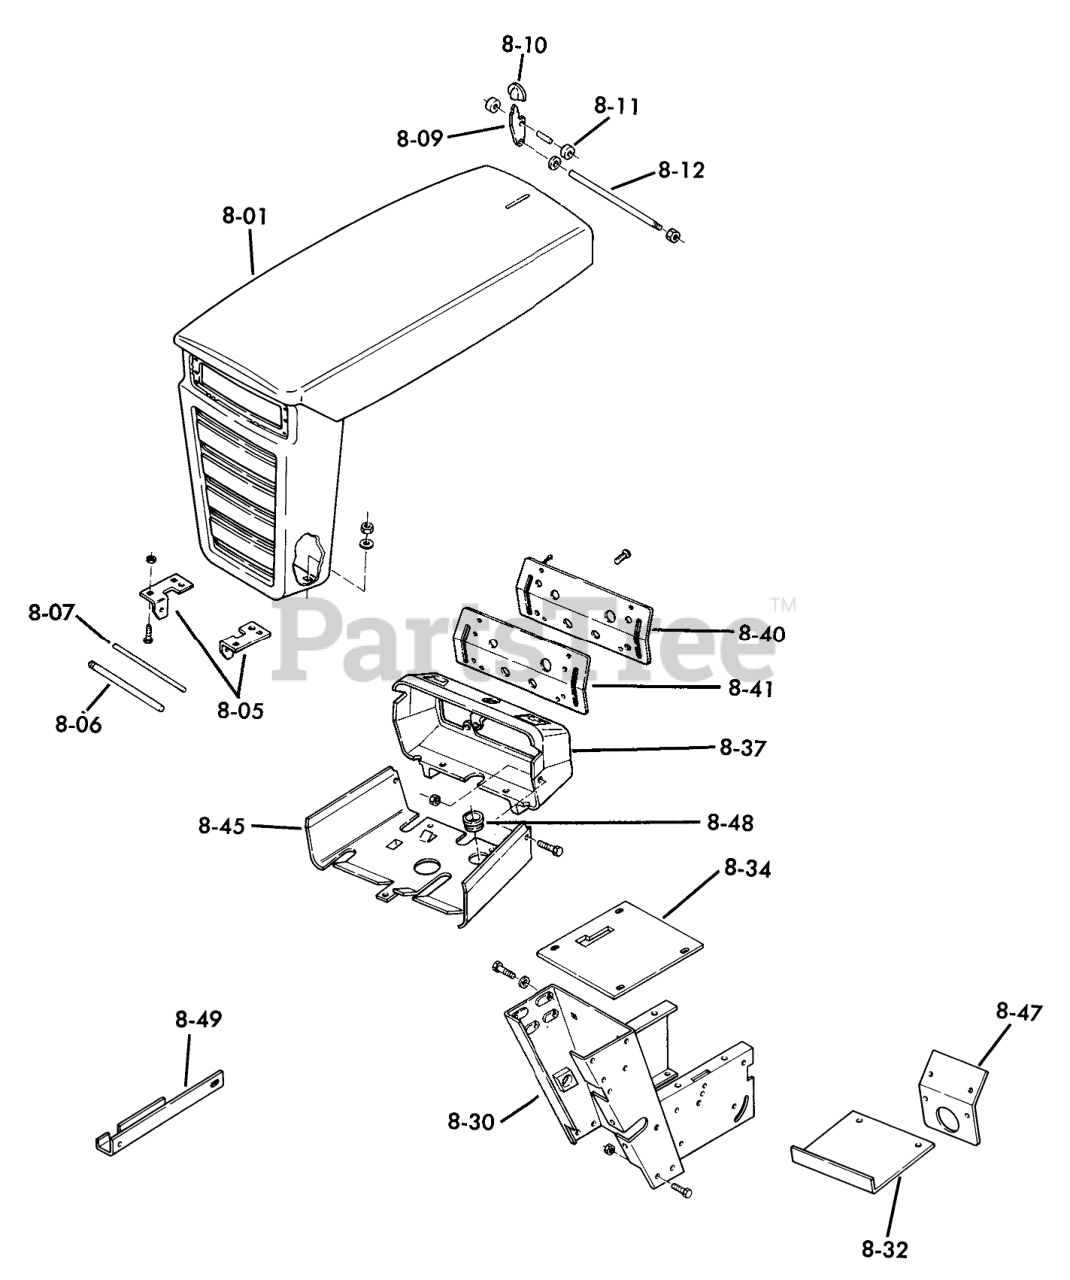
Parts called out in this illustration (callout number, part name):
8-01	Hood
8-05	GRILL PIVOT BRKT
8-05	Bracket-Grille-L.H.
8-05	Bolt
8-05	Nut
8-05	GROMMET
8-06	GRILL PIVOT ROD
8-06	E Ring-3/8
8-07	ROD-HOOD STOP
8-07	Cotter Pin
8-09	LEVER HOOD LATCH
8-09	SPIROL PIN
8-10	KNOB
8-11	Roller
8-12	Rod Latch
8-12	SPEED NUT
8-30	Hoodstand Assembly
8-30	BOLT
8-30	Nut
8-30	Bolt
8-30	Washer
8-30	LOCKWASHER
8-30	Bushing
8-32	Cover-Dust
8-32	Nut
8-34	Cover Plate
8-34	Screw
8-34	Plug Button
8-37	Housing
8-37	Screw
8-37	Nut
8-40	Dash Panel
8-40	PLUG BUTTON
8-41	BACK UP PLATE
8-41	SPEED NUT
8-41	SCREW BLACK
8-41	Tape
8-45	Support-Tank
8-45	Screw
8-45	SPEED CLIP
8-47	Instrument Backet
8-47	Screw
8-48	Grommet
8-49	Channel
8-49	Spacer
8-49	Lockwasher
8-49	Bolt
8-49	Nut
